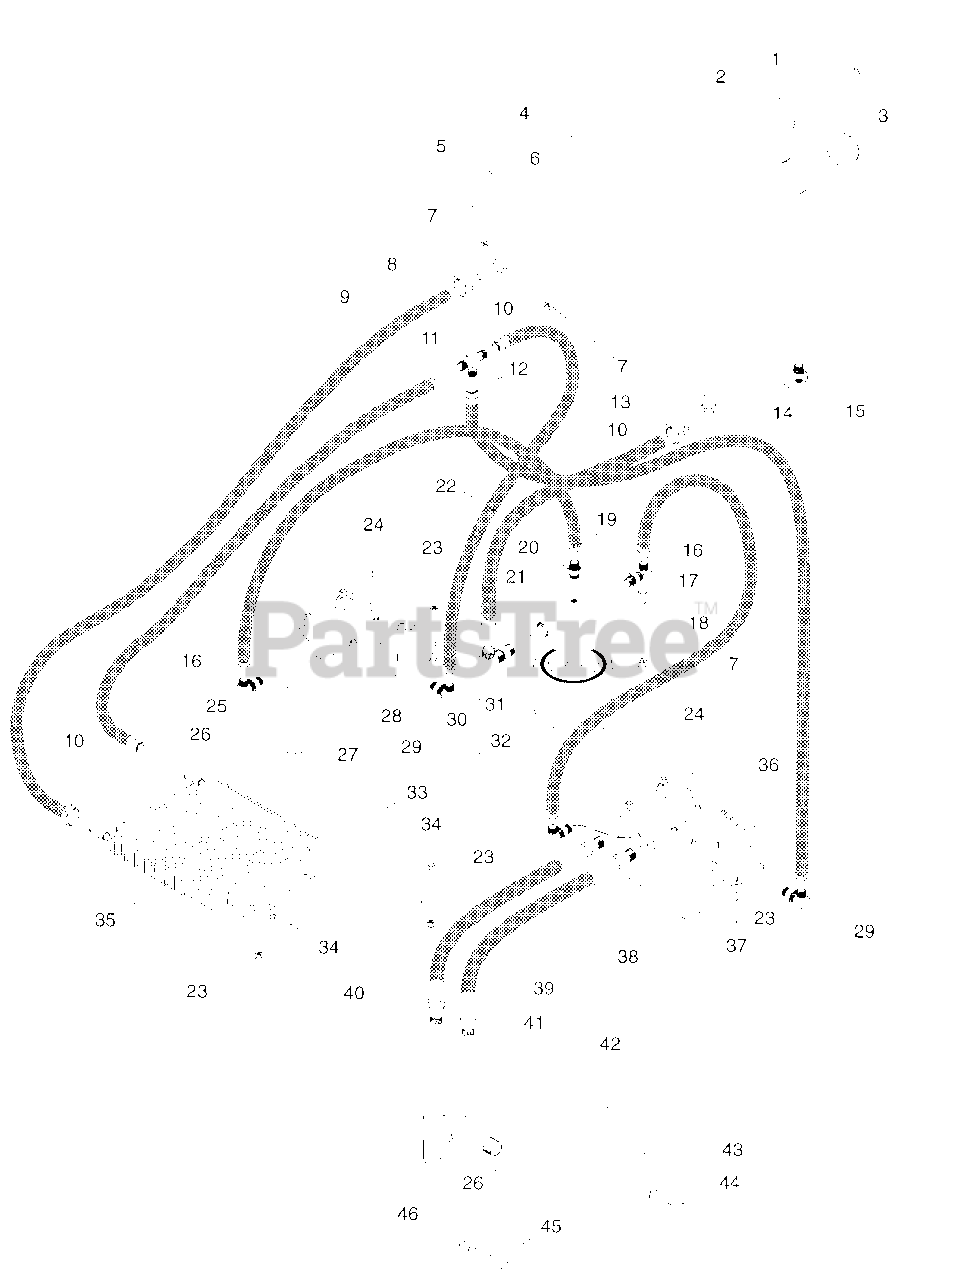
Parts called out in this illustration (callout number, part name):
1	Bolt-Hex .31-18 x 3.50
2	Washer, Flat .344 x 3.0 x .060
3	Cap, Tank
4	Tank, Hydraulic
5	Bolt-Hex .31-18 x .75 Grade 5
6	Bracket, Hydraulic Tank Mounting
7	Nut-Locking-Nylon .312-18 Grade 2
8	Adapter - Male
9	Hose, Oil Cooler to Tank
10	Clamp, .88 Diameter Hose
11	Adapter, Tee, .56-18
12	Hose, Hydraulic Valve to Tank
13	Hose, Pump to Tee
14	Fitting, Elbow, .50 x .50
15	Cock, Drain, .38 x .69 x 1.25
16	Adapter 2503-4-4
17	Bolt-Hex .31-18 x 2.00 Grade 5
18	Bushing, Split, .328 x .462 x .75
19	Hose, Oil Filter to Pump
20	Adapter 0503-4-4
21	Adapter - Pipe .75-16
22	Hose, Tank to Oil Filter
23	Nut-Locking-Nylon .250-20 Grade 2
24	Variable Displace Pump
25	Bolt-Hex .38-16 x 1.125
26	Washer-Flat-Steel .406 x .812 x .065
27	Nut-Locking-Center .625 - 10 Grade 2
28	Bolt-Hex .25-20 x 2.00 Grade 5
29	Adapter 2503-6-6
30	Assembly, Spin-On Lube
31	Assembly, Head
32	Element
33	Bracket, Oil Cooler, Recoil
34	Bolt-Hex .25-20 x .75 Grade 5
35	Cooler, Oil
36	Pin-Dowel .312 x 1.25
37	Arm, Pump Actuating
38	Bolt-Hex .25-20 x 1.25 Grade 5
39	Assembly, Hose, Wheel Motor to Pump
40	Assembly, Hose, Wheel Motor to Pump
41	Motor, Hydraulic Wheel
42	Bracket, Wheel Motor
43	Washer-Lock .375 x .094
44	Bolt-Hex .380-16 x .875
45	Bolt-Hex .38-16 x 1.00 Grade 5
46	Nut-Locking-Nylon .375-16 Grade 2
